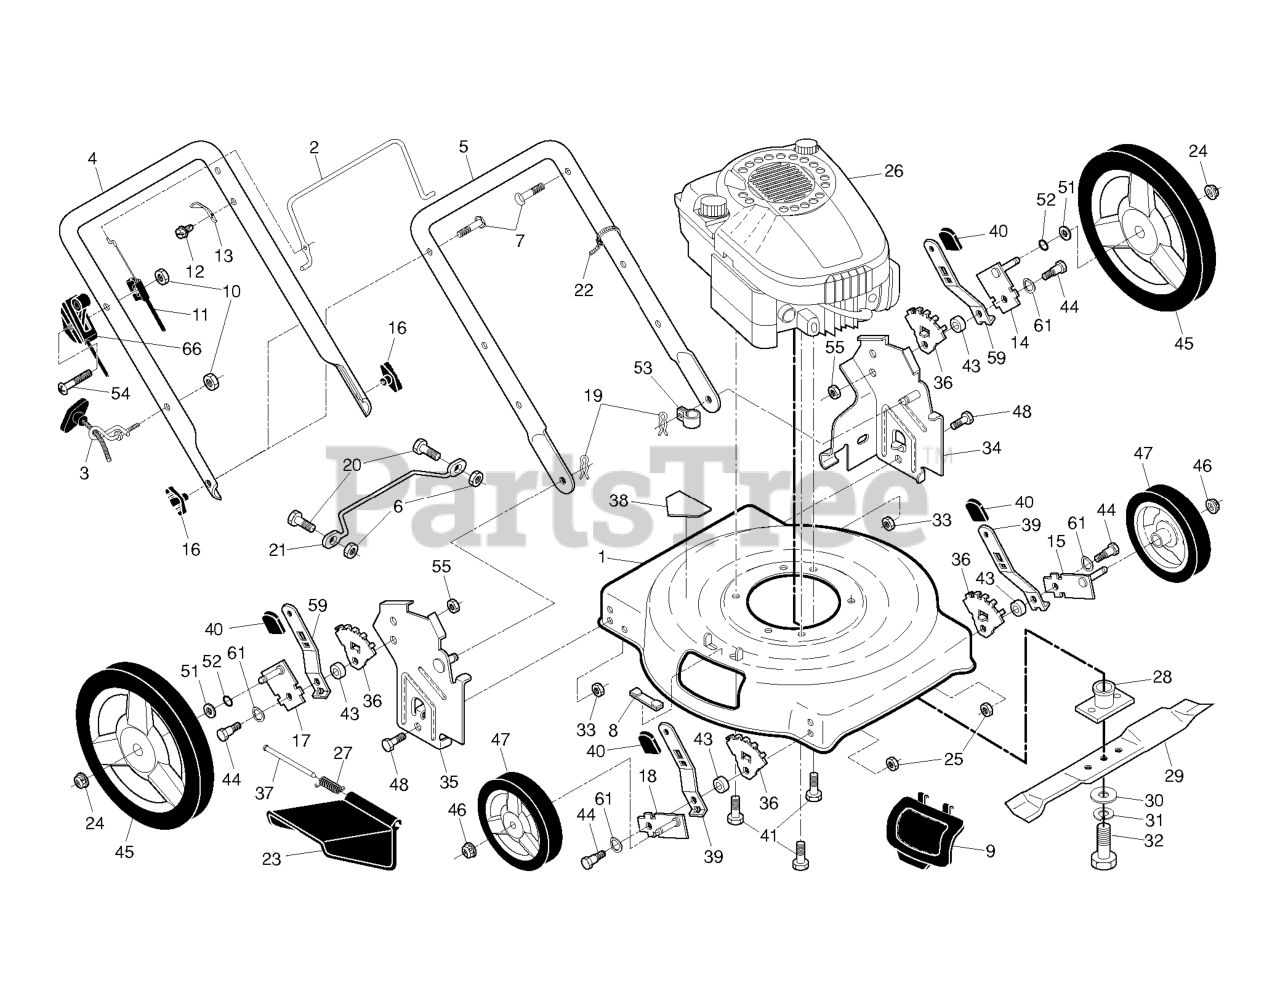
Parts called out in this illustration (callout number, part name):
1	Lawn Mower Housing
2	BAIL.MZR.STD.ORANGE
3	RB GUIDE.ROPE.STD.BLK.ZIN WSL
4	Upper Handle
5	HANDLE.LOWER.GREY
7	BOLT, HANDLE 5/16-18X1.75
8	CLIP. CLOSEOUT
9	PLATE.MULCHER.22.ECON.BLACK
10	NUT
11	Engine Zone Control Cable
13	BRACKET UPSTOP
14	AXLE ARM ASSY REAR LH
15	AXLE ARM ASSY FRONT LH
16	KNOB, DEFLECTOR
17	AXLE ARM ASSY REAR RH
18	AXLE ARM ASSY FRONT RH
19	HAIRPIN COTTER
21	FOOTGUARD.WIREFORM.CE
22	TIE GUIDE
23	GUARD.DISCHARGE.22".
24	NUT.HEX.FLANGE.3/8-16.LOCKNUT
25	NUT.FLANGE.HEX.5/16X18.BLACK
27	SPRING.HINGE
28	ADAPTER.BLADE.W/KEY.25MM.CE
29	Blade, 22"
30	WASHER,HARDEN
31	LOCKWASHER
32	SCREW, HEX HD 3/8-24 X 1-3/8
33	NUT.71038.31-18.HEX.NYLOCK
34	BRACKET.ASM.HANDLE.HW.
35	BRACKET.ASM.HANDLE.HW.RT.ORANG
36	WHEEL ADJ BRACKET FRONT
38	DECAL.INTERNATIONL.CUTFINGER
39	SELECTOR SPRING, FRONT
41	BOLT 3/8-16X1-1/8
43	SPACER.HEIGHT.ADJUSTER
44	SHOULDER BOLT 5/16-18
45	RP.WHEEL.12X1.75H 3 SPOKE.RAD
46	NUT.HEX.FLANGE.3/8-16.LO(3 2)
47	WHEEL AND TIRE ASSY, REAR
48	BOLT
51	WASHER.FLAT.1/2
52	O-RING..070X.487.NEOPRENE
53	CLIP.CABLE.BLK
55	NUT.LOCK.5/16-18
59	SPRING.SEL.EXT.21.DOMED.12/14
61	WASHER.CURVED.CYLINDRICAL
66	Control Throttle
